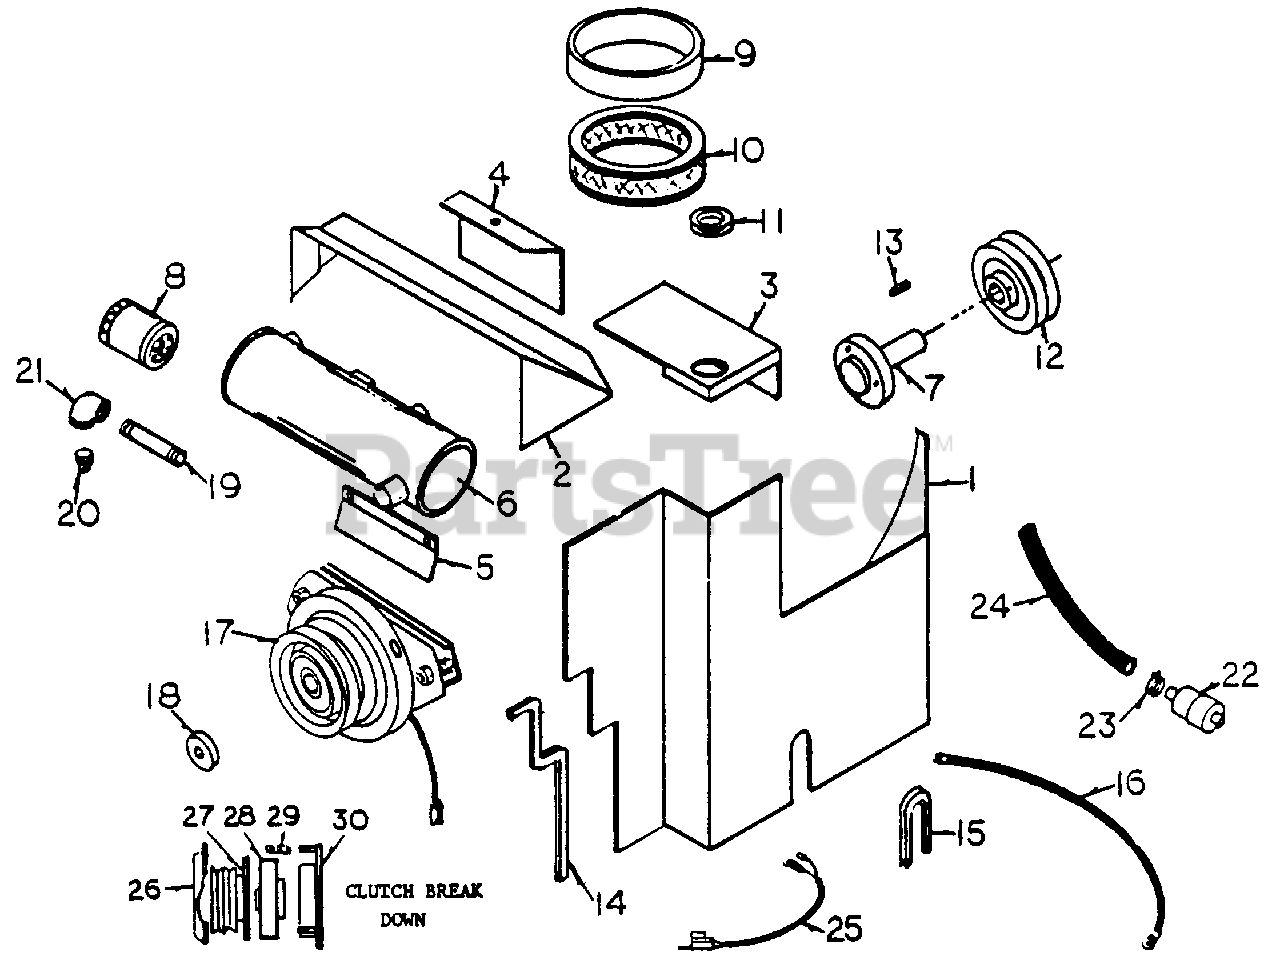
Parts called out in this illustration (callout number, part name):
1	Heat Shield, Part A
2	Heat Shield, Part B
3	Heat Shield, Part C
4	Heat Shield, Part D
6	Muffler
7	Englne Shaft
8	0il Filter
9	Filter Element
10	Filter Cartridge
13	Key Stock, 1/4" x 1"
17	Elcctrlc Clutch
18	Clutch Retainer Washer
19	Pipe Nipple, 3/8"
20	Pipe Plug, 3/8"
21	Pipe Elbow, 3/8"
22	Fuel Filter
23	Fuel Line Clamp
24	Fuel Line, 38"
25	Starter Harness
29	Clutch Brake Sprlng
